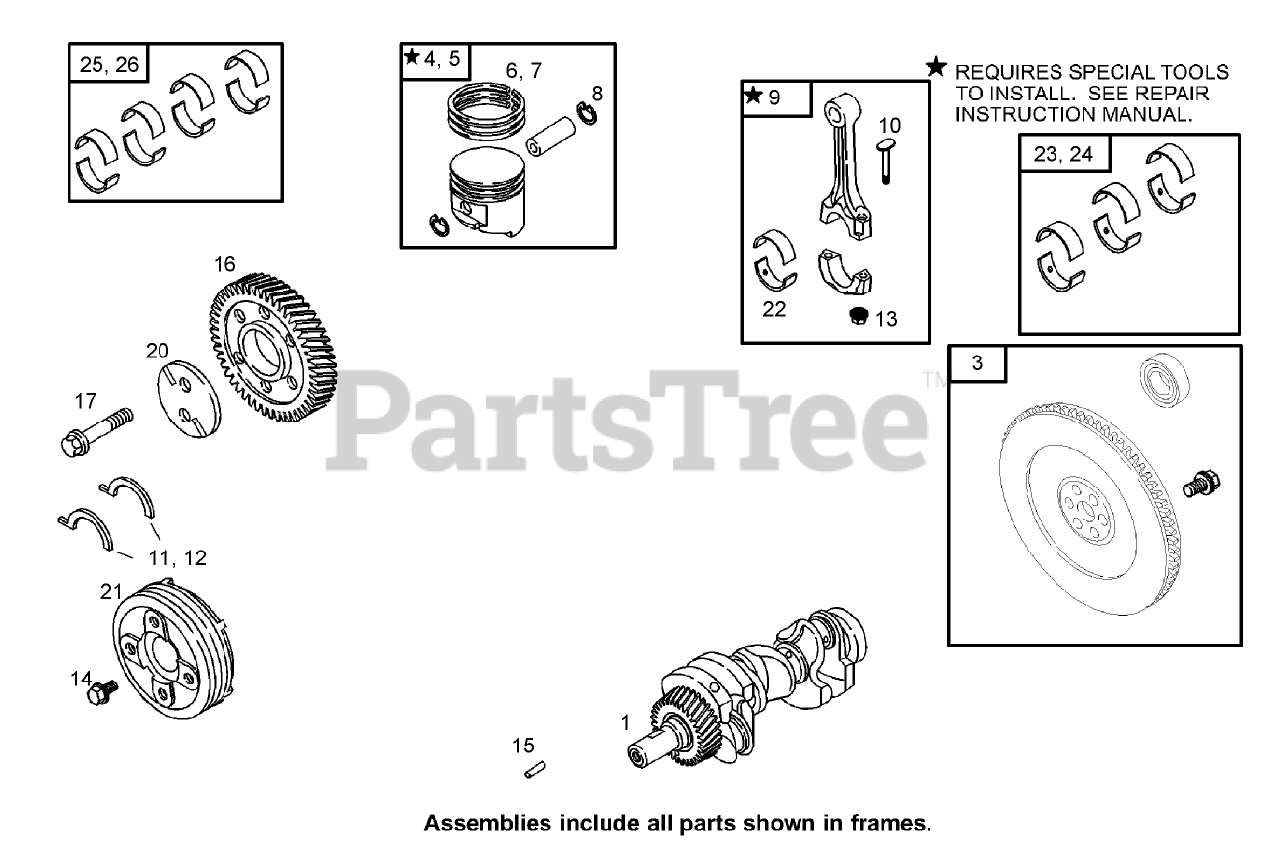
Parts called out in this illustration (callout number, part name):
1	Crankshaft
3	FLYWHEEL
4	PISTON ASM
5	PISTON ASM (OVERSIZE)
6	Ring Set
7	RING SET (.010 OVERSIZED)
8	LOCK-PIN, PISTON
9	ROD-CONNECTING
10	SCREW-ROD, CONNECTING
11	WASHER-THRUST
12	WASHER-THRUST (.005 IN OVERSIZED)
13	NUT-HEX
14	SCREW-HEX
15	PIN-LOCATING
16	GEAR-DRIVE
17	SCREW-HEX
20	PLATE-GEAR, IDLER
21	PULLEY-CRANKSHAFT
22	BEARING-ROD
23	SET-BEARING, ROD
24	SET-BEARING, ROD (.010 UNDERSIZED)
25	SET-BEARING, MAIN (SET OF 8)
26	SET-BEARING, MAIN (.010 UNDERSIZED)
